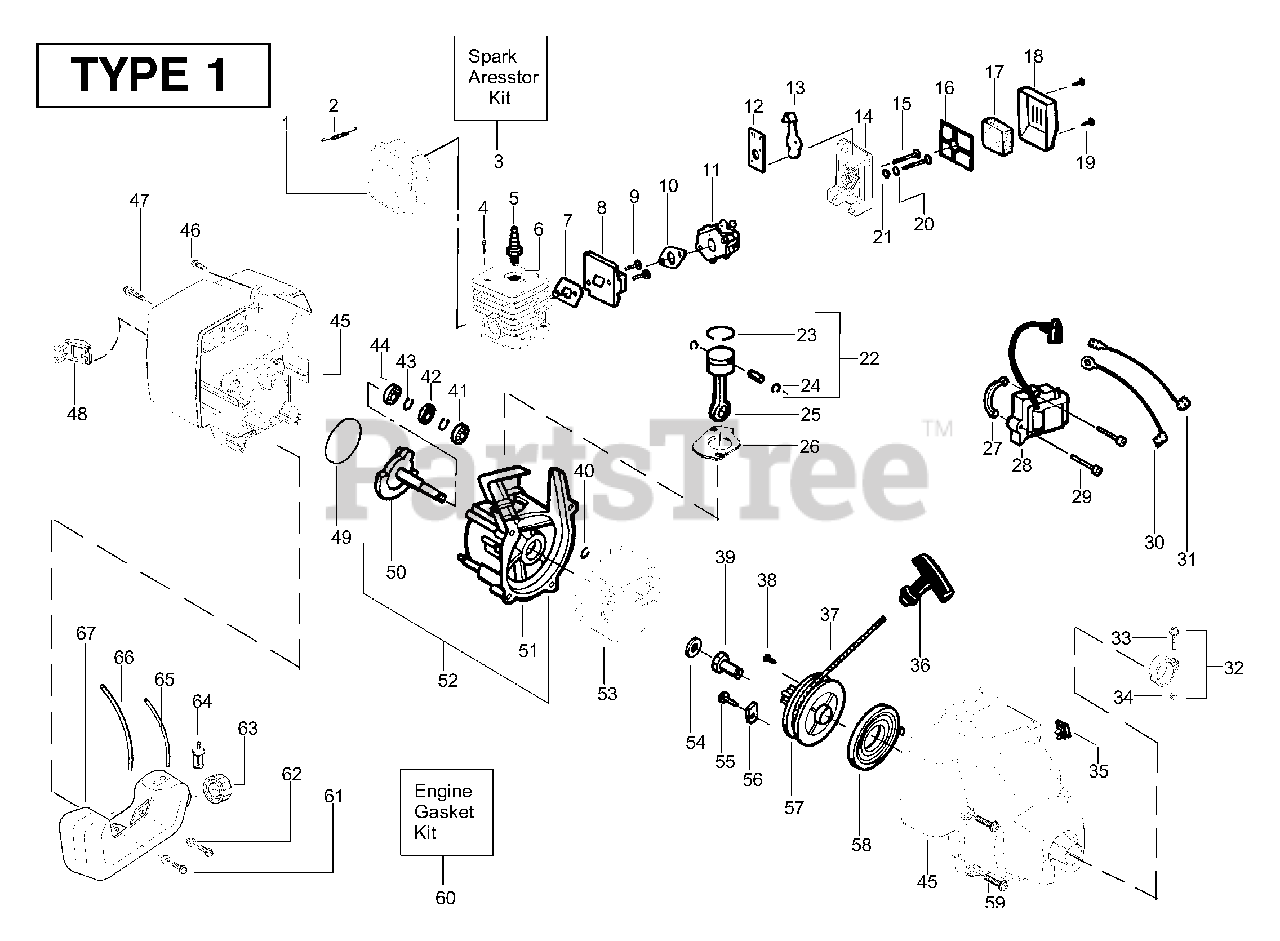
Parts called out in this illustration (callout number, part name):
1	Kit - Muffler
2	Spring-Muffler
3	Kit-Spark Arrestor
4	Screw-Cylinder
5	Spark Plug (RCJ-8Y)
6	Kit - Cylinder
7	Gasket-Cylind./Carb.
8	Adapter-Carb.
10	Gasket-Carb.
11	Kit - Carburetor Ass'y
12	Choke Plate Mounting
13	Shutter-Choke
16	Plate - Filter Support
17	Foam-Air Filter
18	Cover-Air Filter
20	Spacer-Choke
22	Kit - Piston
23	Piston Ring
24	Retainer-Piston Pin
25	Assy-Connecting Rod
26	Gasket-Cylinder
27	Spacer-Module
28	Ignition Module
30	Assy-Ground Wire
31	Assy-Leadwire
32	Assy-Nose Cone Clamp
33	Screw-Nose Cone
34	Nut-Nose Cone
35	Kit-Switch
36	Handle-Starter
37	Kit - Rope
39	Coupling-Drive
40	Retain. Ring-C'shaft
41	Outer Bearing
42	C'case Seal
43	Retainer Ring-C'case
44	Inner Bearing
45	Assy.-Fan Hsg/Shroud
47	Screw
48	Guard-Muffler
49	O-Ring-C'case/Shrd
50	Assy-Crankshaft
51	Assy-Crankcase
52	Assy-C'case & C'shaft
53	Assy-Flywheel
54	Washer-Flat
56	Retainer-Can
57	Kit-Starter Pulley
58	Spring-Starter
59	Screw
60	Kit-Engine Gasket
63	Assy-Fuel Cap
64	Assy-Fuel Pickup
65	Kit-Fuel Line (Small)
66	Kit-Fuel Line (Large)
67	Assy-Fuel Tank
